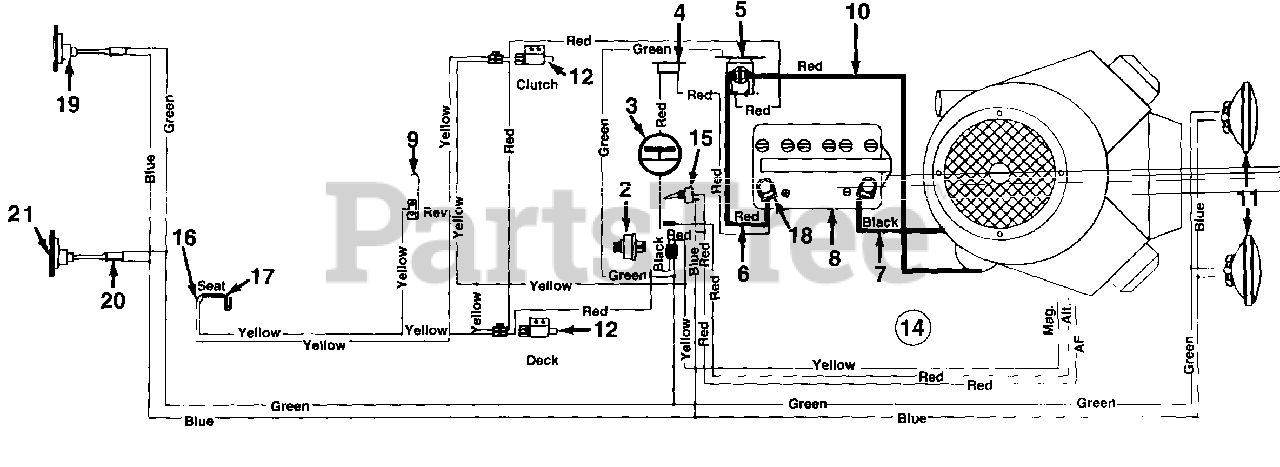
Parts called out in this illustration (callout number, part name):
2	Ignition Switch
3	Ammeter
4	Circuit Breaker 20 Amp
5	Solenoid
6	Electric Wire
7	Electric Wire
8	Battery
9	Spring Switch (Reverse Safety)
10	Electric Wire
11	Headlights
12	Safety Switch (PTO & Clutch)
14	Wire Harness
15	Light Switch
16	Safety Switch (Seat)
17	Safety Switch (Seat)
18	Battery Boot
19	Taillight
20	Taillight Harness
21	Taillight Bulb
